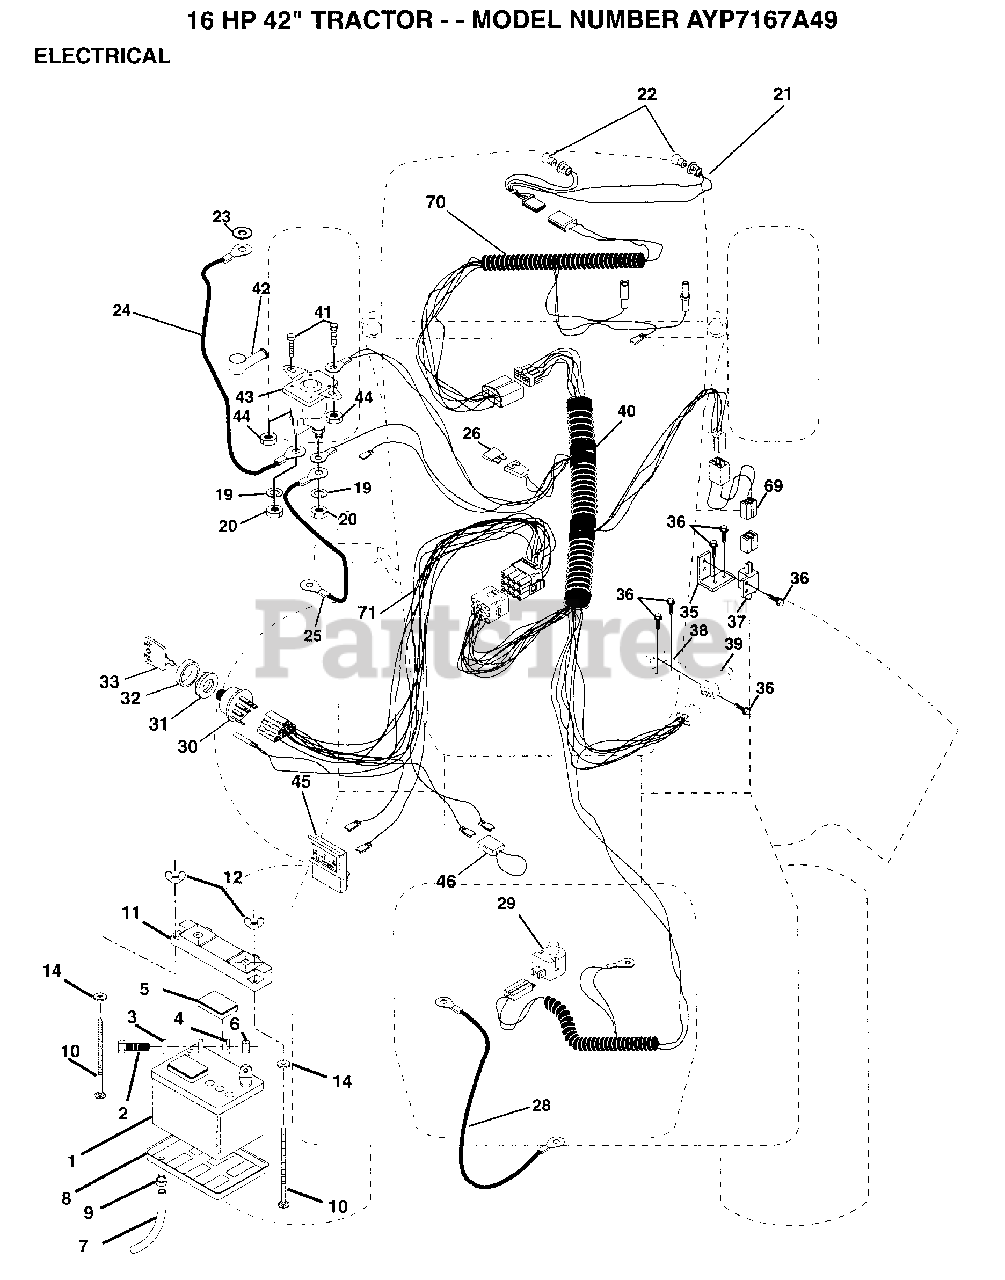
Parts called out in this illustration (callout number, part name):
2	BOLT LT
3	WASHER
4	LOCKWASHER
5	"CAP,BATTERY "
7	"DRAIN TU T, BATT"
8	"TRAY T, BATTERY"
9	HOSE CLAMP T
10	BOLT
14	WASHER.3/4X1X18GA
18	CLIP PUSH - IN
20	NUT
21	"HARNESS,LIGHT SOC"
22	HEADLAMP BULB
23	LOCKWASHER
24	CABLE-BATTERY T
25	"CABLE T, BATTERY"
26	FUSE HYT
28	CABLE T
29	SWITCH SEAT
30	SWITCH IGN 4POS
31	NUT IGNITION
32	COVER KEY SWITCH
33	KEY
35	BRACKET LT
36	SCREW
37	SWITCH-INTER. GT
38	BRACKET SWITCH IN
39	SWITCH INTERLOCKT
40	HARNESS IGN B&S
41	BOLT HXHD FIN
44	NUT HXKEP 1/4X20
45	AMMETER
46	PROTECTION LOOP
69	ADAPTER.HARN.SERV
70	HARNESS.ENG.LT.
71	HARNESS DASH LT
72	CLIP PUSHIN SPRIN
73	CLIP PUSH IN
